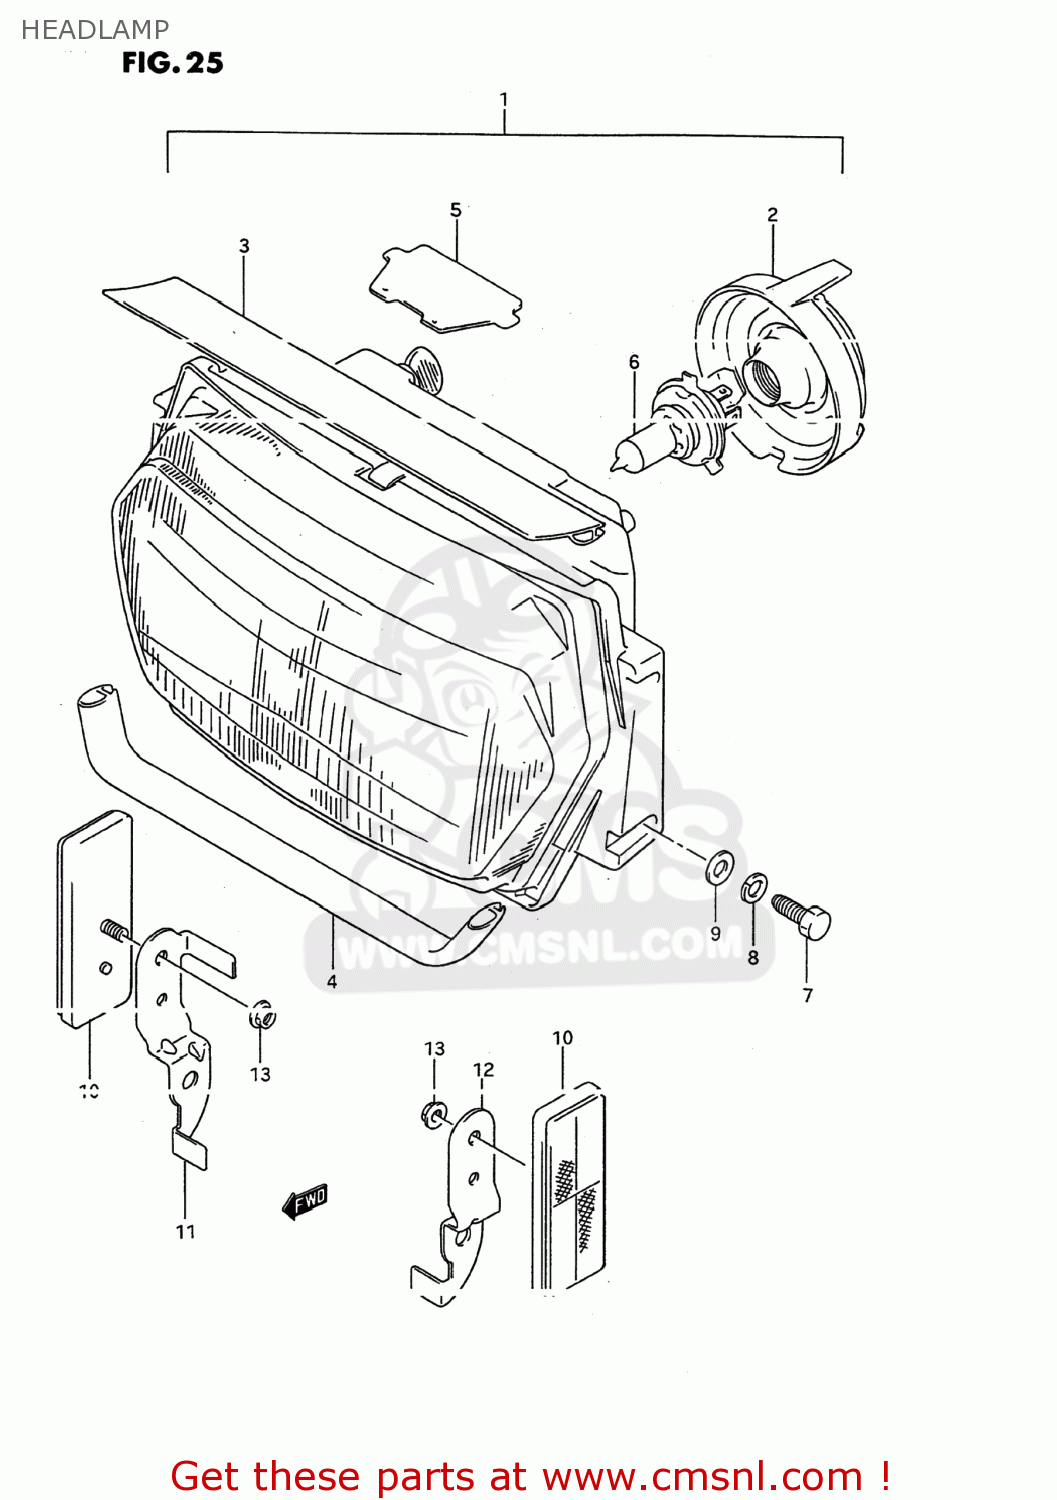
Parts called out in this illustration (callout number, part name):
1	HEADLAMP ASSY
2	COVER,SOCKET
3	GASKET,HEADLAMP (NAS)
4	GASKET,HEADLAMP (NAS)
5	GASKET (NAS)
6	BULB(12V60/55W,H4)
7	BOLT
8	LOCK WASHER
9	WASHER
10	REFLEX REFLECTOR,FR SIDE
11	BRACKET,FR SIDE RR,R
12	BRACKET,FR SIDE RR,L
13	NUT
